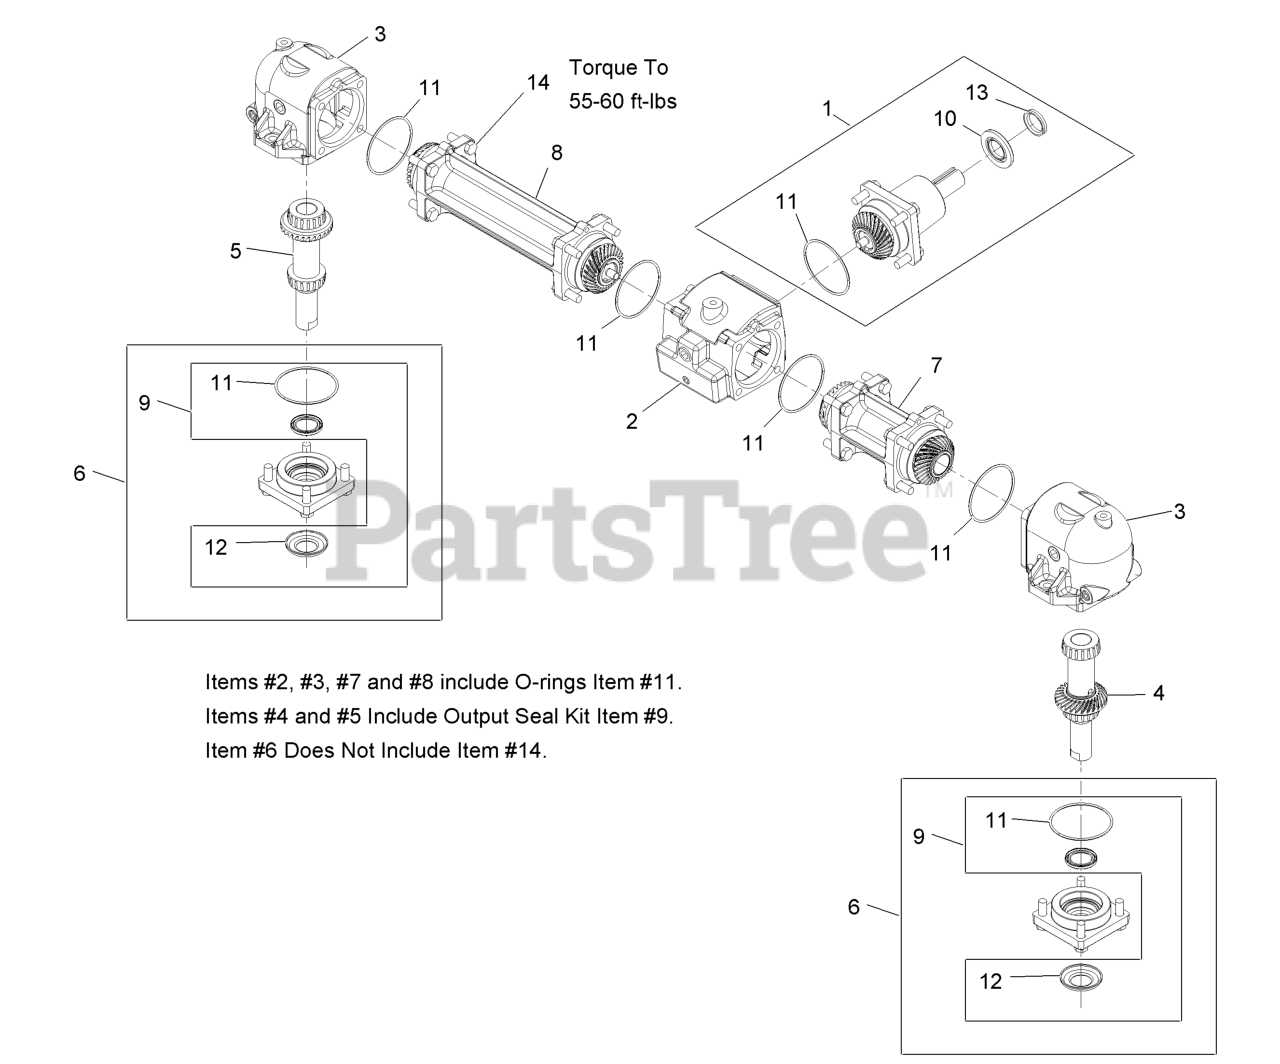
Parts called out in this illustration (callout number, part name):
1	INPUT PINION ASM
1	PINION-INPUT
2	HOUSING-CENTER
3	HOUSING-END
4	LH OUTPUT SHAFT AND GEAR
5	RH OUTPUT SHAFT AND GEAR
6	CAP-OUTPUT
7	TUBE-CONNECTOR, SHORT
8	TUBE-CONNECTOR, LONG
9	OUTPUT SEAL KIT
10	SEAL-INPUT
11	SEAL-O-RING
12	WASHER-CUPPED
13	SEAL-V-RING
